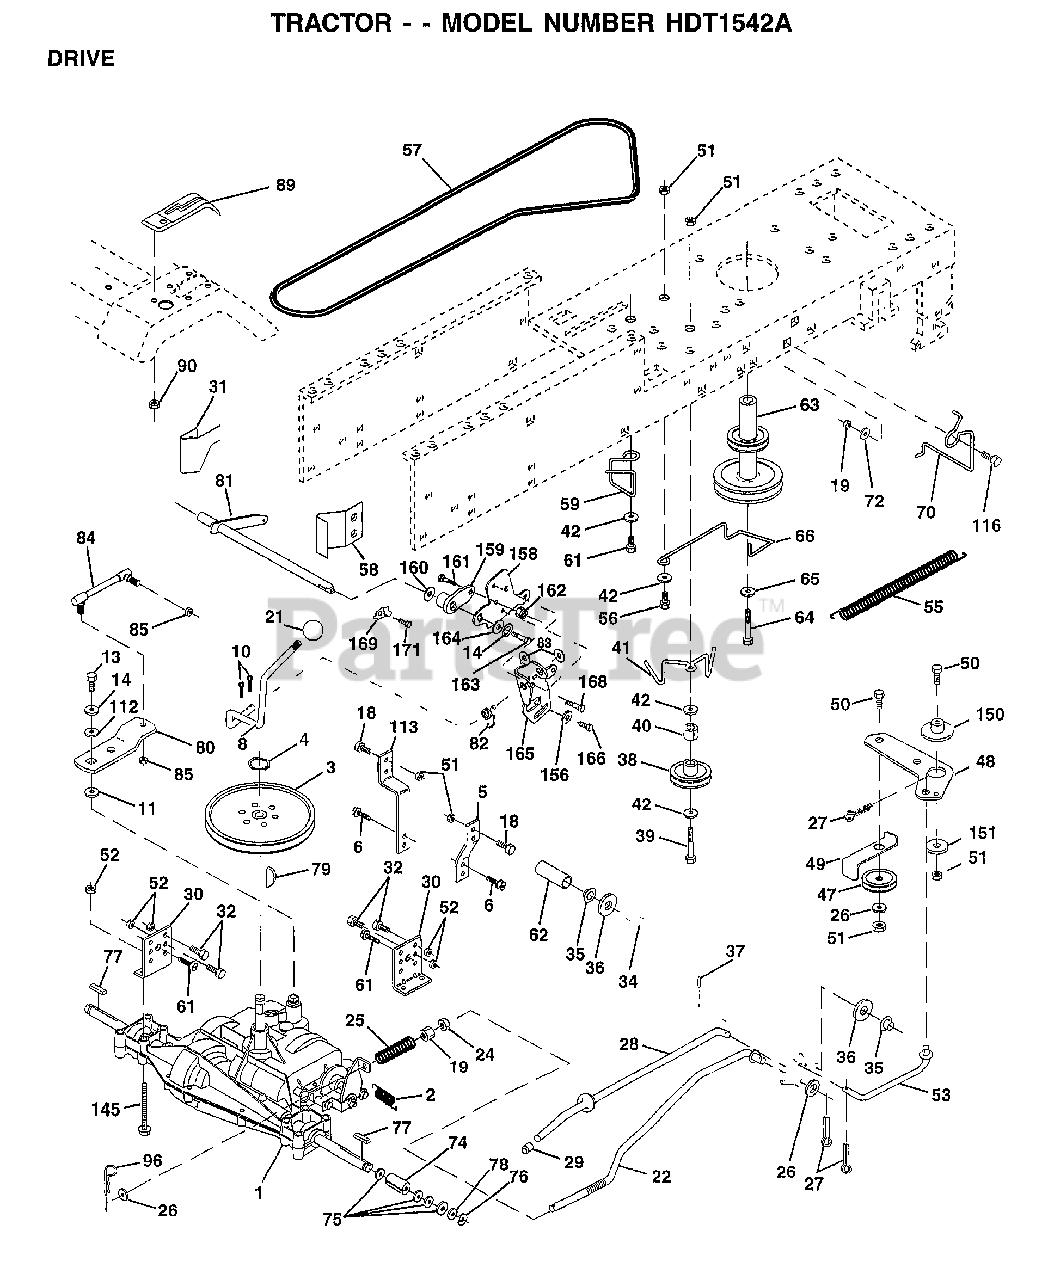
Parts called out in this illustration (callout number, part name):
2	SPRING.BRAKE.RETU
3	PULLEY TRANS
5	STRAP TORQUE
6	SCREW
8	ROD.SHIFT.FENDER.ADJ.LT.CRD
10	PIN COTTER 1/8
11	WASH-SHFT PLT LT
13	BOLT.1/4-28.W/PAT
14	LOCKWASHER
18	BOLT
19	NUT
21	KNOB T (1/2-HOLE)
21	"KEEPER,BELT LH T"
22	BRAKE ROD
24	NUT
25	SPRING ROD LT
26	WASHER
27	COTTER PIN
28	ROD.BRAKE.PARK.LT
29	PLUNGER CAP T
30	TRANSAXLE MTG BKT
32	BOLT
34	SHAFT ASM-PEDAL F
35	NYLON BEARING
36	WASHER LT
38	FLAT IDLER PULLEY
39	BOLT
40	SPACER T
41	"KEEPER,BELT.IDLER FLAT"
42	WASHER
48	BELLCRANK.CLUTCH
49	RETAIN BELT
53	"LINK, CLUTCH T"
55	"SPRING, RETURN LT"
58	"KEEPER,BELT RH T"
59	KEEPER BELT CNTSP
61	SCREW
62	PEDAL COVER T
63	PULLEY.ENGINE
64	BOLT
65	LOCKWASHER
66	KEEPER-BELT
70	KEEPER BELT ENG
72	WASHER
74	SPACER AXLE
75	WASHER
76	E-RING LT
77	SQUARE KEY
78	WASHER
80	"ROD,LINK SHIFT"
81	SHAFT.ASM.CROSS
82	"SPRING,TORSION"
83	WASHER
84	LINK.TRANSAXLE
85	NUT.CNT.LOCK.1/4
89	CONSOLE.SHIFT.SLT
90	NUT
96	RETAINER M
112	WASHER LT
113	"STRAP,TORQUE"
116	BOLT RDHD 3/8-16
145	BOLT.HEX.FLGHD
150	BUSHING.BELLCRANK.GRD.DR
151	WASHER
156	WASHER.SRRTD.5/16
158	BRKT.SHIFT.MOUNT
159	HUB.SHIFT
160	WASHER
161	BOLT T
164	WASHER.5/8X.281X10GA
165	BRKT.PIVOT.LEVER
166	SCREW.5/16-18X5/8
168	BOLT.SHOULDER.5/16-18X.561
169	PLATE.FASTENING
171	SCREW LT
